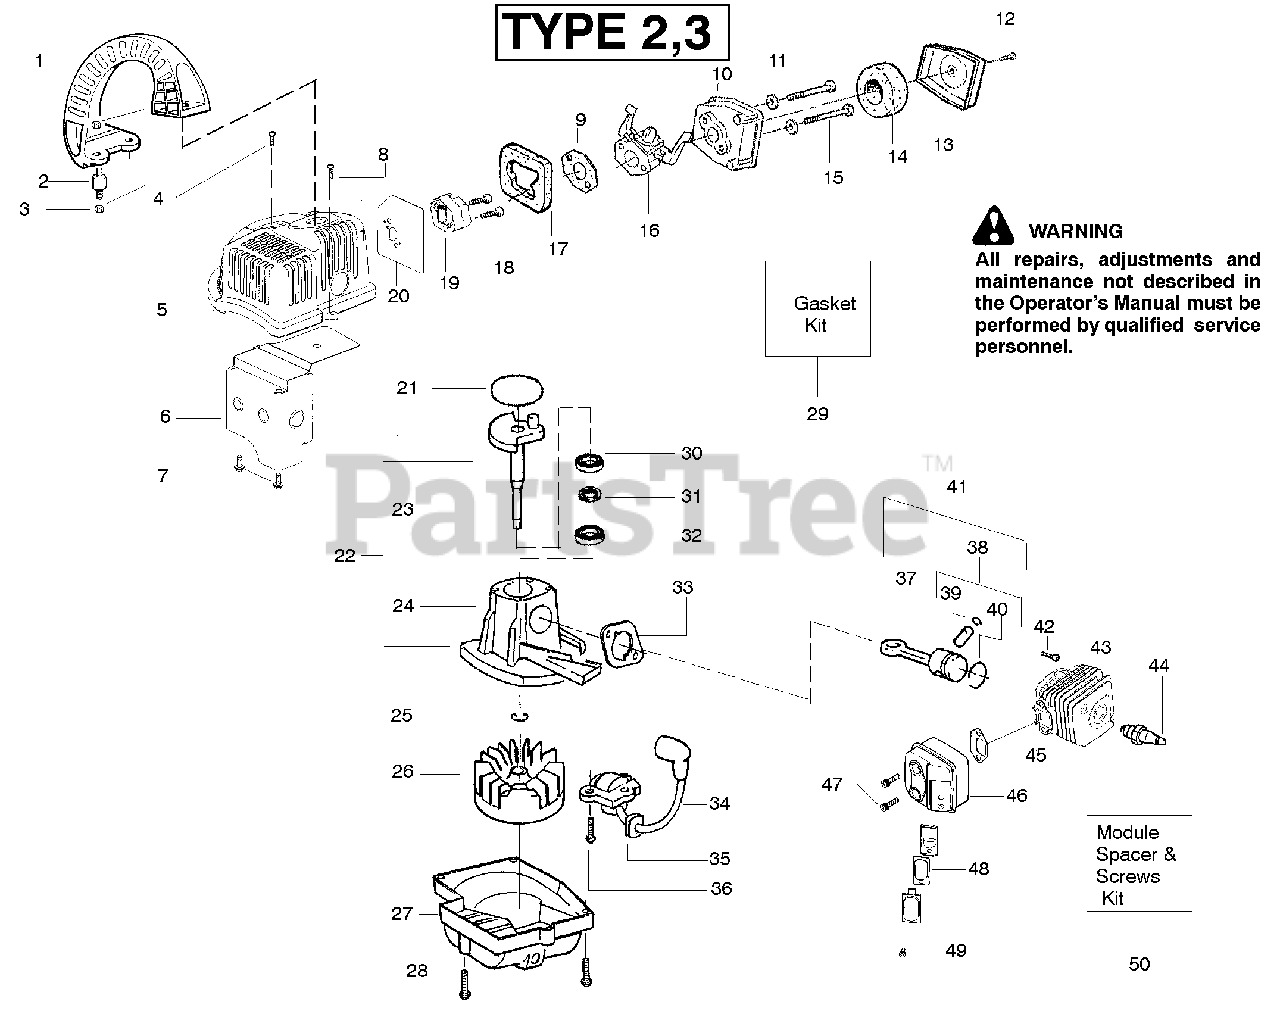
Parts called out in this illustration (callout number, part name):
2	Isolator-Handle
4	Screw
6	Shield-Heat
7	Screw
9	Gasket-Carb. (Kit)
11	Washer
13	Cover-Air Box
14	Foam-Air Filter
16	Kit-Carburetor Ass'y. (C1U-W12A)
17	Foam-Air Dam
19	Adaptor-Carb.
20	Gasket-Cyl/Carb. Adaptor (Kit)
21	Gasket-C'case/Shroud (Kit)
22	Assy.-C'case & C'shaft
23	Assy.-Crankshaft
24	Assy.-Crankcase
25	Retainer Ring (C'shaft)
26	Assy.-Flywheel
27	Fan Housing
28	Screw
29	Kit-Gasket
30	Inner Bearing
31	Seal-Crankcase
32	Bearing-Outer
33	Gasket-Cylinder (Kit)
34	Ignition Module
35	Grommet-Ign. Module
37	Kit-Connecting Rod Assy.
38	Kit-Piston
39	Wrist Pin Retainer
40	Piston Ring
41	Kit-Piston/Rod Assy.
43	Cylinder
44	Spark Plug (RCJ-6Y)
45	Gasket-Muffler (kit)
46	Kit-Muffler
47	Bolt-Muffler
48	Kit-Spark Aresstor
50	Kit-Module spacer/screws
